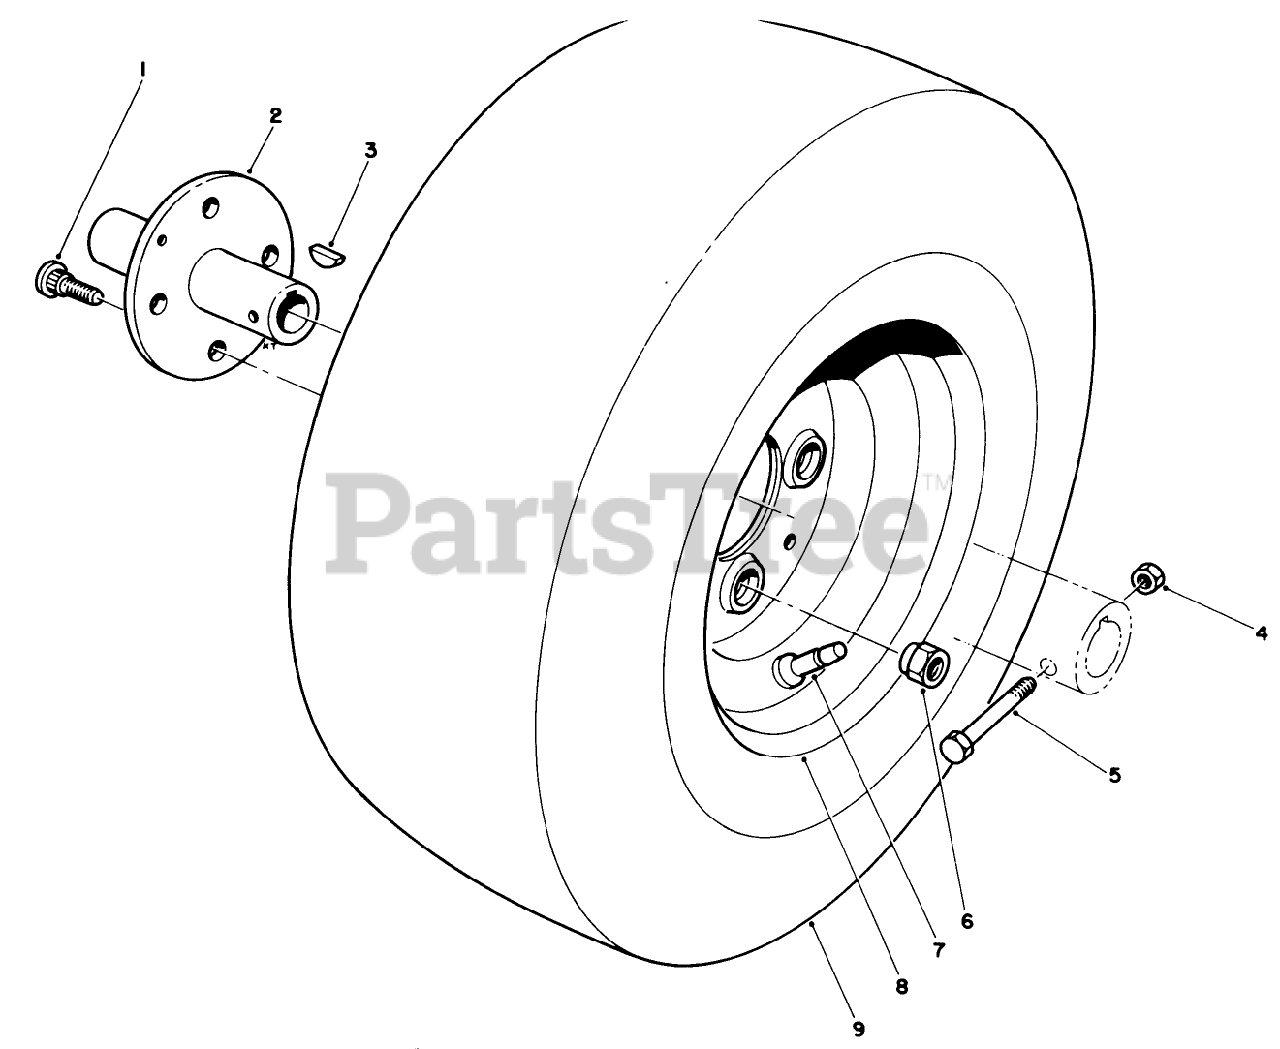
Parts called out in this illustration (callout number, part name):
1	1/2-20X1.25 BOLT
2	WHEEL HUB
3	KEY-WOODRUFF
4	NUT-LOCK, NI
5	SCREW-HH
6	NUT-LUG
7	Valve Stem w/Cap
9	TIRE-4-Ply
